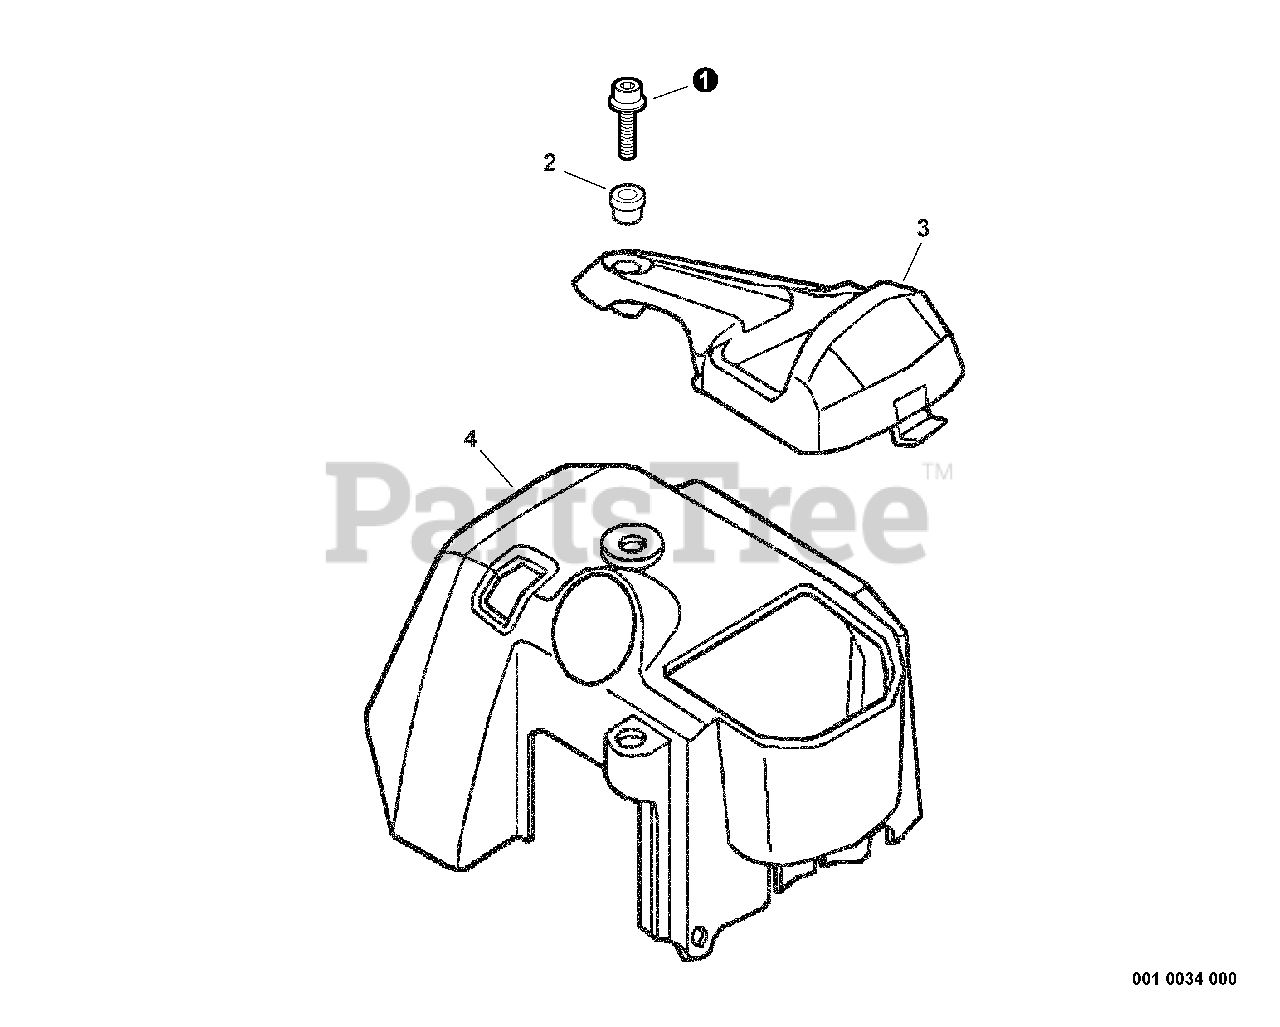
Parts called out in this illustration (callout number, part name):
1	BOLT 5×16
2	COLLAR 5
3	GUARD, TOP - GRAY
3	GUARD, TOP - ORANGE
4	COVER, ENGINE - GRAY
4	COVER, ENGINE - ORANGE
